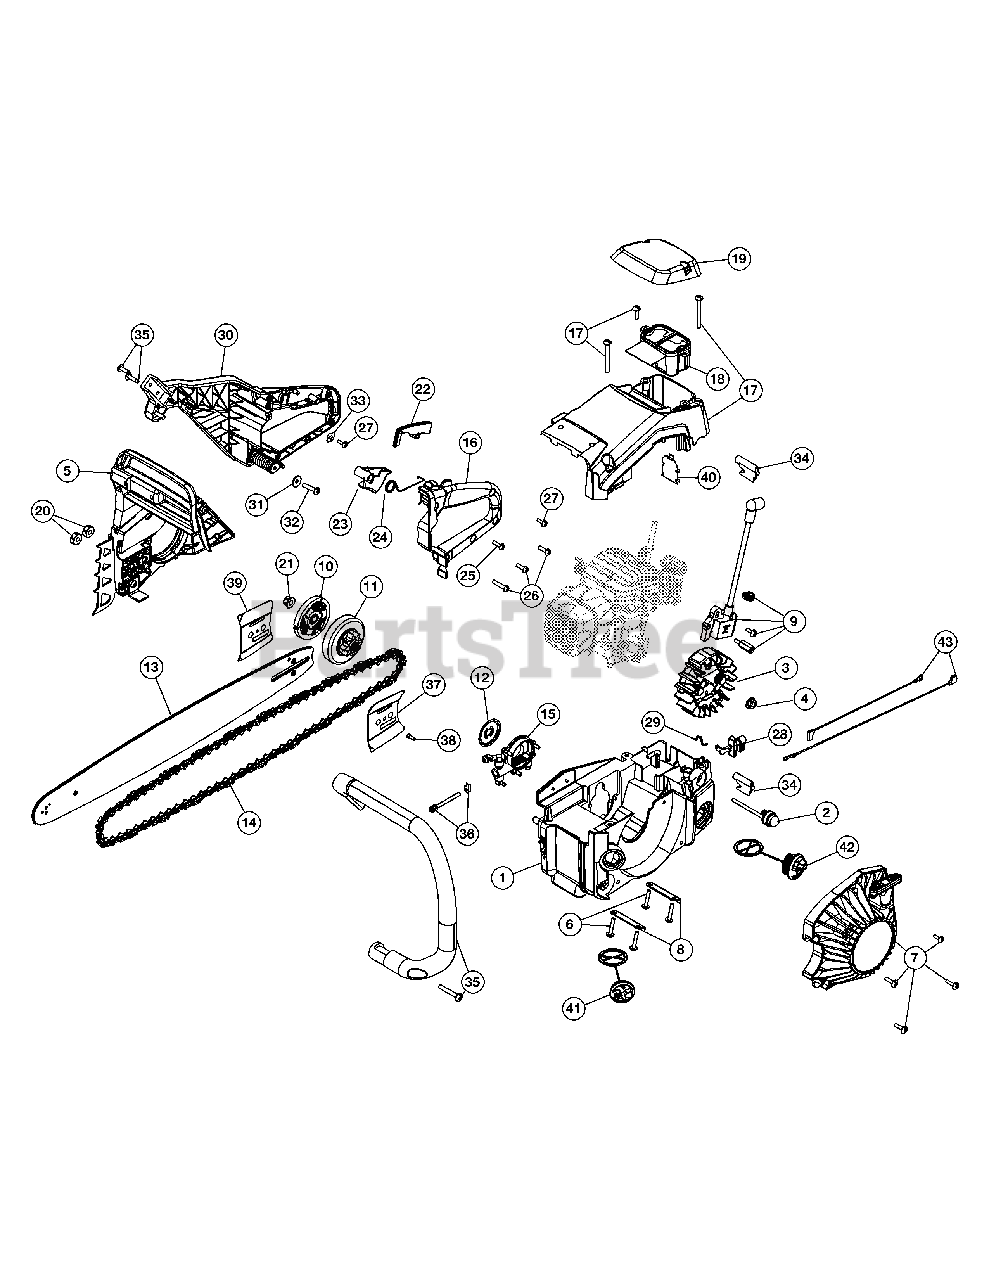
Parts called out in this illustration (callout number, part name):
1	Housing Assembly (Incl. 2, 41 & 42)
2	Primer Bulb Assembly
3	Flywheel Assembly
4	Flywheel Nut
5	Chain Brake Assembly
6	Engine Mount Screw
7	Starter Housing Assembly
8	Engine Mount Plate Assembly (Incl. 6)
9	Module Assembly
10	Clutch
11	Clutch Drum Assembly
12	Oil Pump Shield
13	Bar
14	18" Chain
15	Oil Pump Assembly
16	Rear Handle Cover Assembly w/switch
17	Top Cover Assembly (Incl. 40)
18	Air Cleaner Assembly
19	Air Cleaner Cover Assembly
20	Bar Nut
21	Clutch Nut
22	Trigger Release
23	Throttle Trigger
24	Trigger Release Spring
25	Upper Grip Screw
26	Lower Grip Screw
27	Throttle Clamp Screw
28	Choke Lever Assembly
29	Choke Rod
30	Rear Handle Assembly
31	Grip Anti-vibration Washer
32	Grip Anti-vibration Screw
33	Throttle Clamp Washer
35	Handle Assembly
36	Tension Screw & Nut Assembly
37	Inner Guide Plate
38	Guide Plate Screw
39	Outer Guide Plate
40	Screen
41	Oil Cap
42	Fuel Cap
43	Ground Wire
